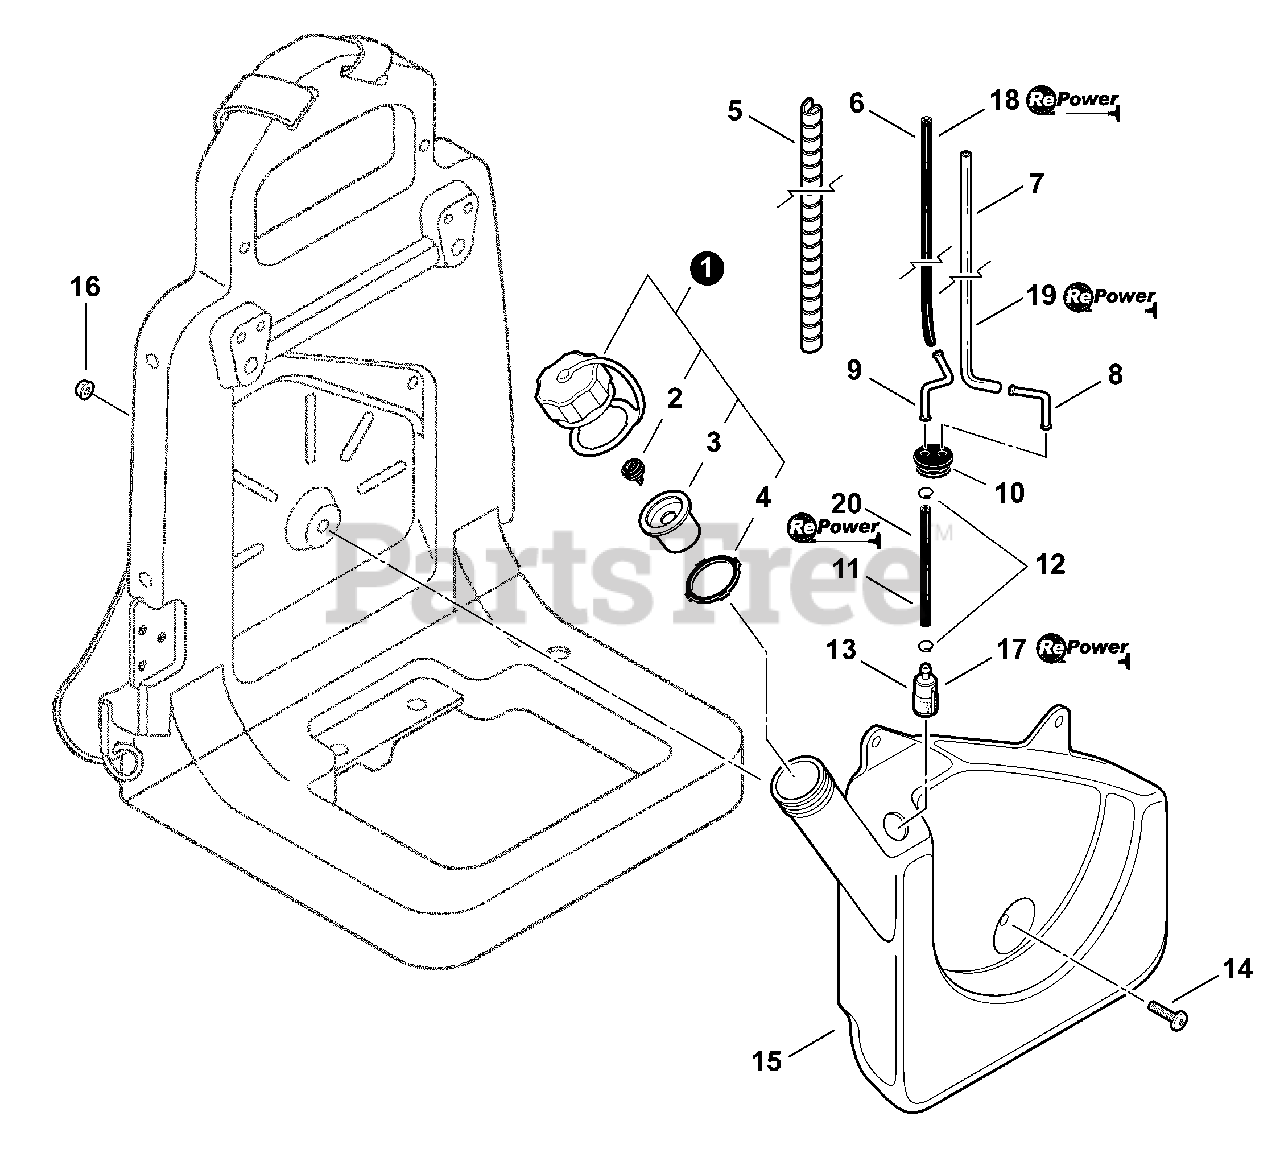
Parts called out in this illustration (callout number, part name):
1	CAP ASSY
3	VENT HOLDER ASSY
4	GASKET, CAP
5	WRAP, SPIRAL
6	PIPE, FUEL - 3×7×465
7	PIPE - 2×4×470 -- CLEAR
8	CONNECTOR, PIPE
9	CONNECTOR, PIPE
10	GROMMET
11	PIPE - 3×6×280 -- BLACK
12	CLIP - 6.5
13	FILTER, FUEL
14	SCREW - 5×20
15	TANK, FUEL
16	NUT - 5 -- FLANGE
17	RePower TUNE-UP KIT
18	PIPE - 25 FT BULK 3×7mm
19	PIPE - 25 FT BULK 2×4mm CLEAR
20	PIPE - 25 FT BULK 3×6mm BLACK
